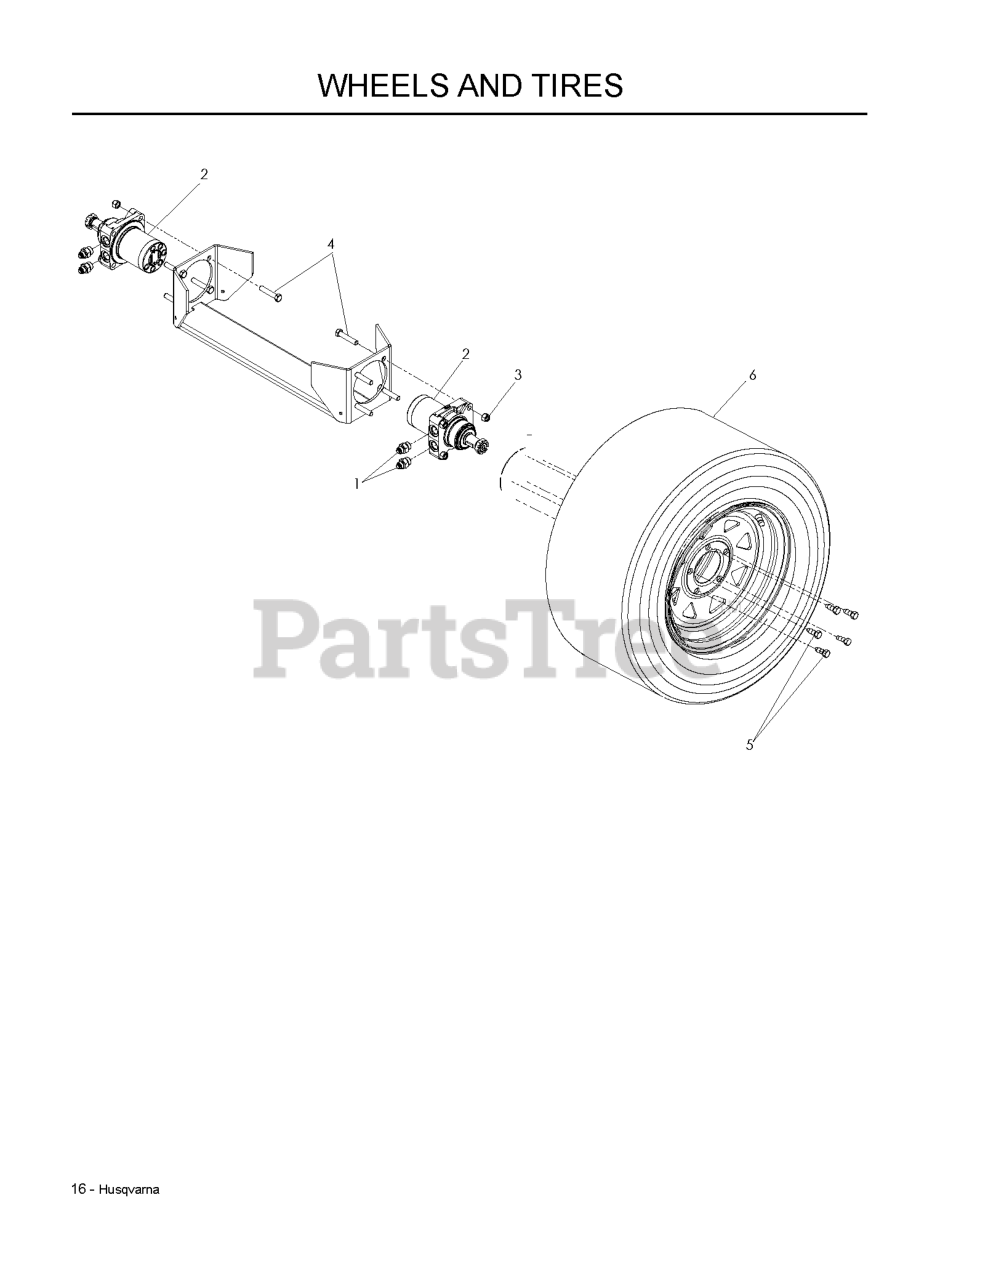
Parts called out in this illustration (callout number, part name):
1	CONNECTOR, STRAIGHT
2	WHEEL MOTOR, TJ
3	NUT 1/2-13 HEX NYLOC ZD
4	HEX SCREW 1/2-13 X 2.5" GR 5
6	WHEEL.R.TS.23X10.5-12.C.MS
